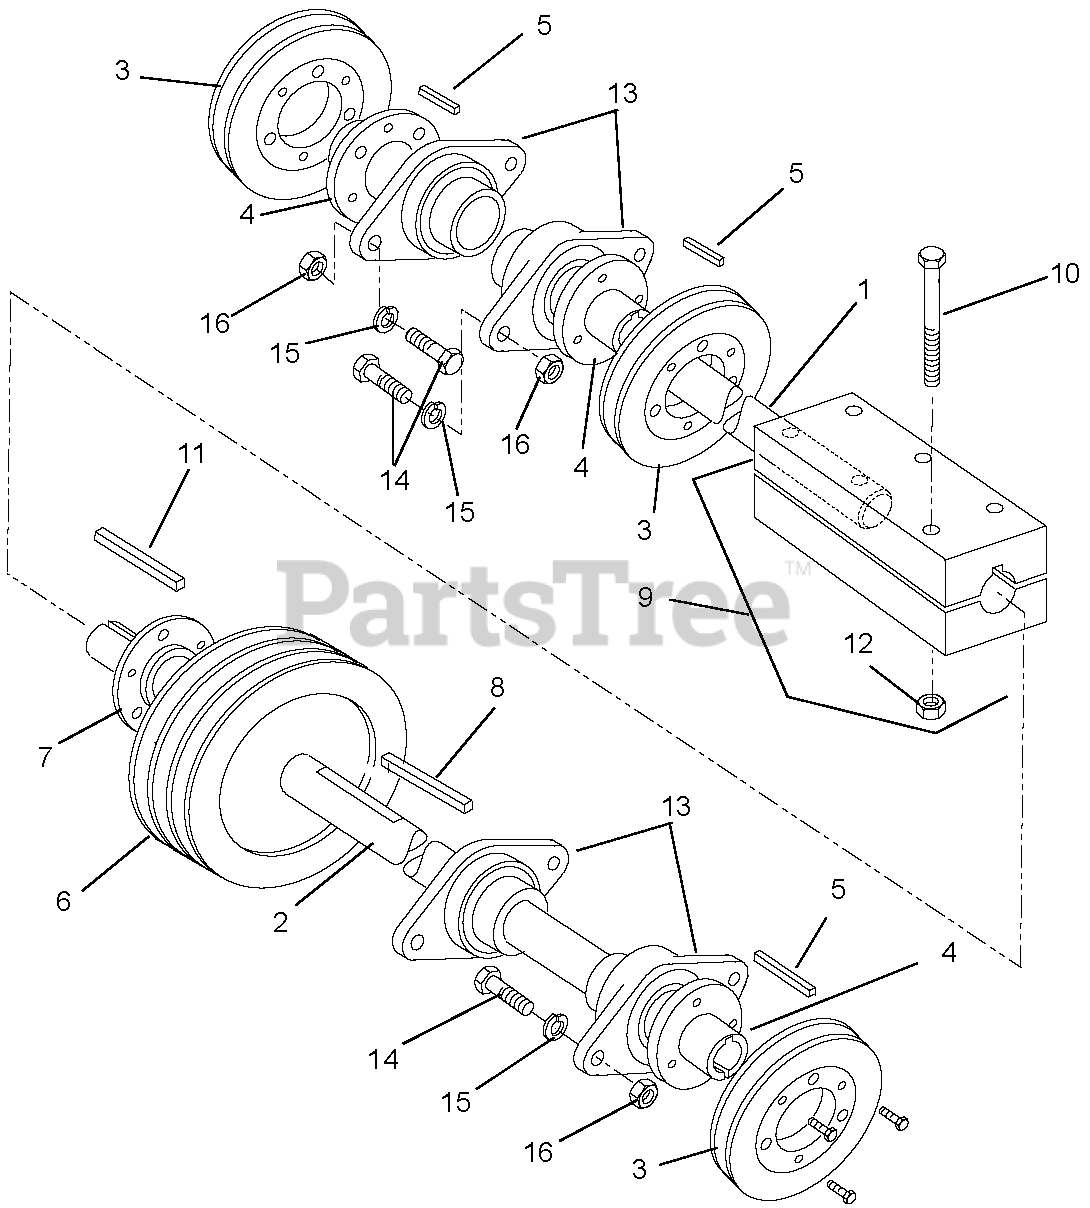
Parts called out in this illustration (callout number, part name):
1	Jackshaft, Right Rear
2	Jackshaft, Left Rear
3	Pulley, Taper Lock
4	Bushing, Split Tapered
5	Key, Square .25 x .25 x 1
6	Pulley, 3-Belt 6.6 PD
7	Bushing, Split Tapered
8	Key .25 x .25 x 3
9	Assembly, Jackshaft Coupling
10	Cap Screw, Hex Head .312-18 x 2.5
11	Key .25 x .25 x 5
12	Nut, Nylock Hex .312-18
13	Flange, Bearing 2-Bolt
14	Cap Screw, Hex Head .437 x 1.25
15	Washer, Lock .437
16	Nut, Hex .437
